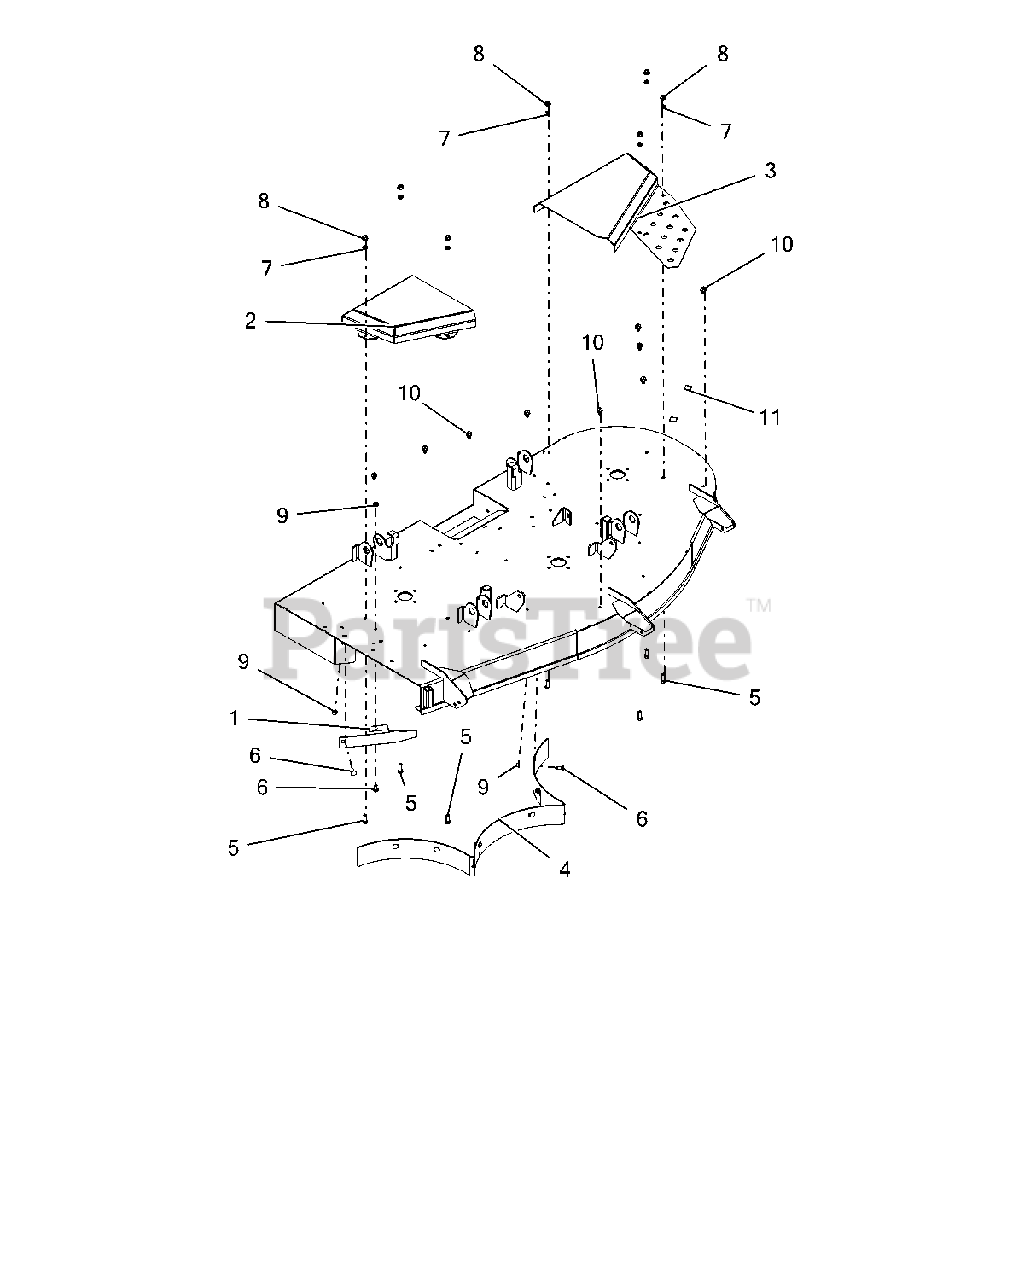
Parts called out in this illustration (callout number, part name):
1	BAFFLE, DISCHARGE 60
2	COVER, RH BELT 60
3	COVER, LH BELT 60
4	BAFFLE, REAR BOLT-IN, 60" XL
5	@BLT-HEX .38-16X1.00 GR5 YWZC
6	@BLT-RDHDSQNK .31-18X.75 G5YZ
7	NUT-HEX-JAM .375-16 YWZC
8	@NUT-LK-TOP-FLG .38-16 YWZC
9	@NUT-LK-TOP-FLG .31-18 YWZC
10	@SCR-TAP .38-16X.50 HWH TR YWZ
